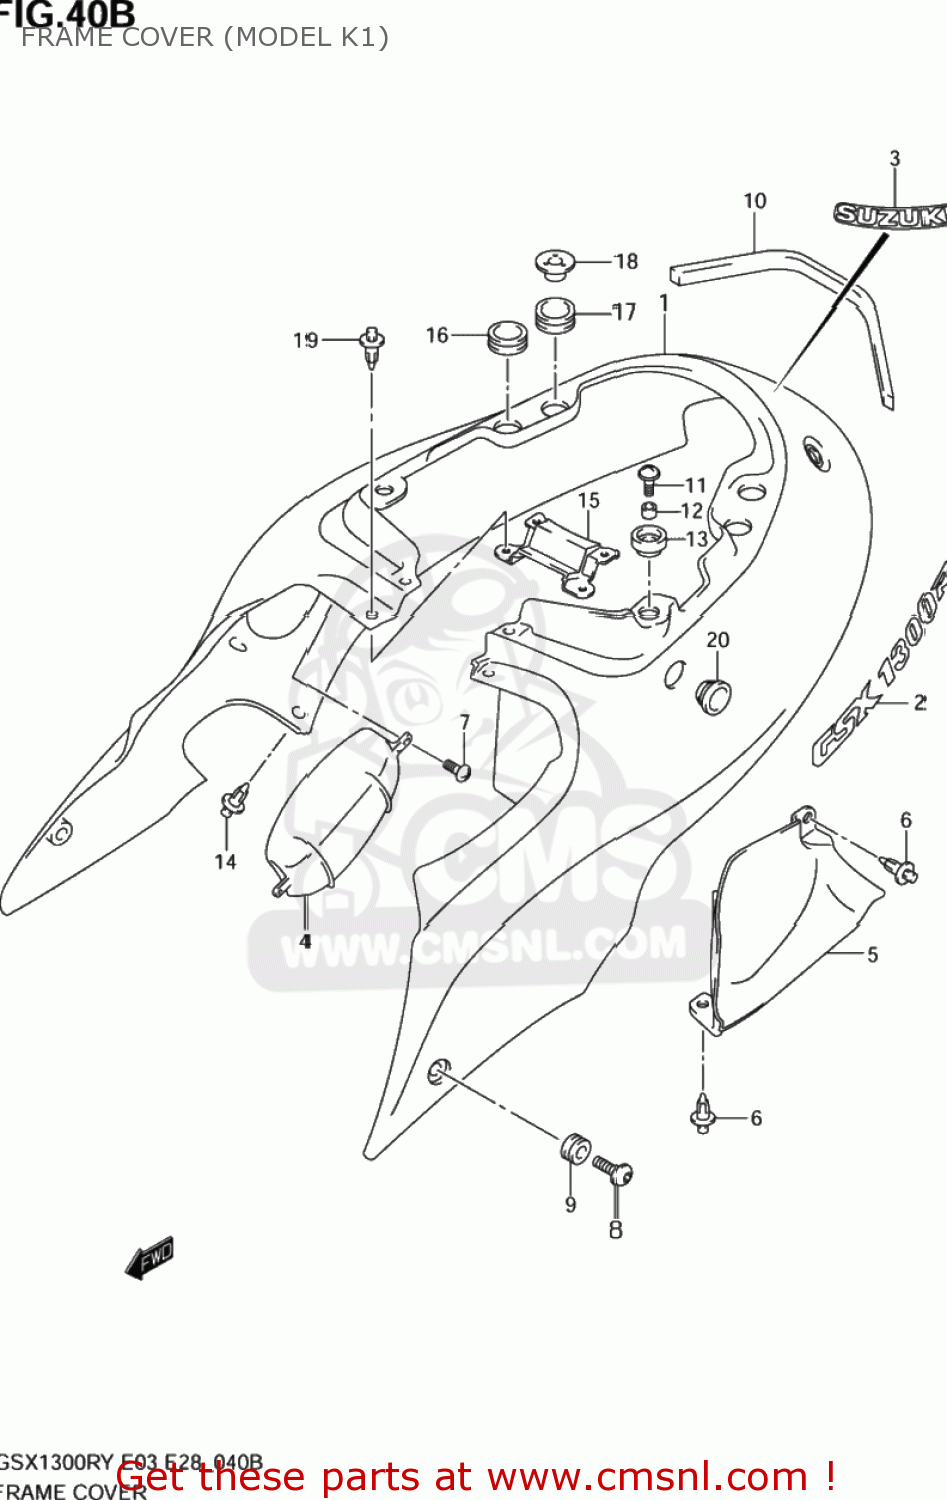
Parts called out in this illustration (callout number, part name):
1	COVER COMP,FRA
2	EMBLEM,FRAME COVER
3	EMBLEM,SUZUKI
4	CAP,FRAME COVER HOLE,R
5	CAP,FRAME COVER HOLE,L
6	CLIP(BLACK)
7	SCREW
8	SCREW(6X20)
9	CUSHION
10	CUSHION,FRAME COVER UPR
11	SCREW(6X20)
12	SPACER(6.5X10X11)
13	CUSHION
14	CLIP(BLACK)
15	COVER,FRAME CTR
16	CUSHION,FRAME COVER UPR RR
17	CUSHION,FRAME COVER UPR RR RR
18	WASHER,FRAME C
19	CLIP(BLACK)
20	CUSHION,FRAME COVER CTR
